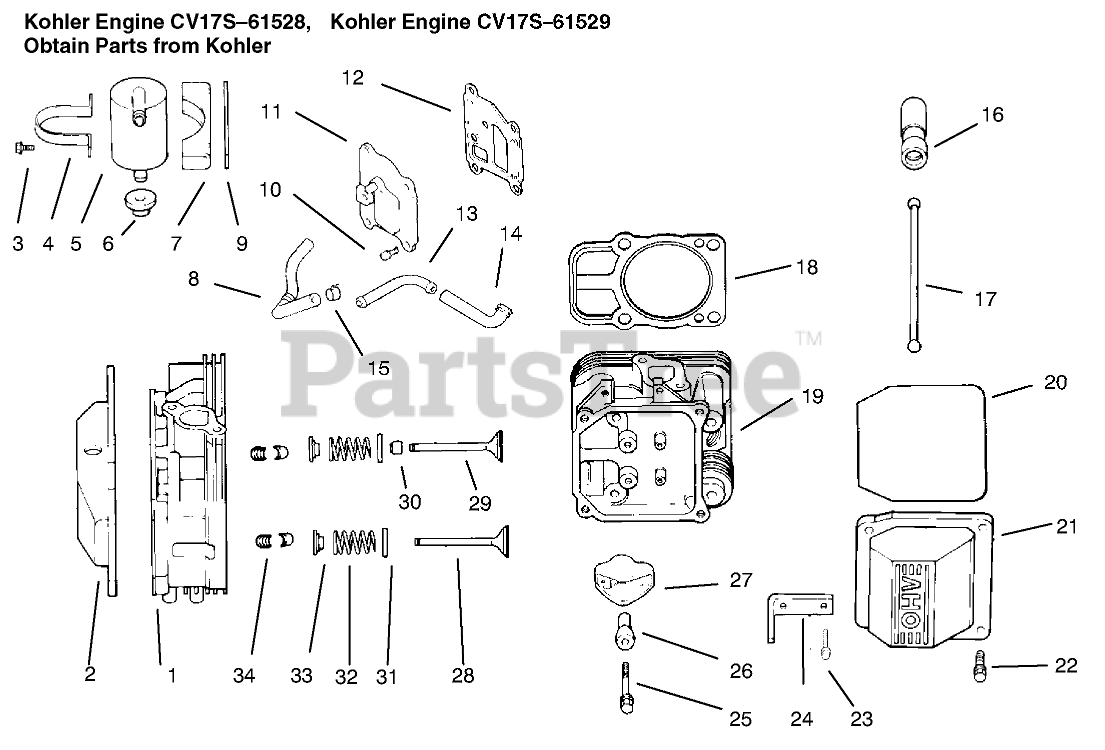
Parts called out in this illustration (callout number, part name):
1	#1 Cyl. Head Asm
2	Kit-Valve Incl 6 20-22
3	Screw-HF
4	Strap-Lifting
5	Kit-Breather Incl 3-9
6	Grommet-Rubber
7	Bracket
8	Hose-Breather
9	Spacer
10	Screw
11	Cover-Breather
12	Gasket-Breather
13	Fitting
14	Hose-Breather
15	Clamp
16	Lifter-Valve
17	Rod-Push
18	Gasket-Cylinder Head
19	#2 Cyl. Head Asm,
20	O Ring
21	Valve Kit
22	Screw
23	Screw
24	Strap-Lifting
26	Pivot-Arm, Rocker
27	Arm-Rocker
28	Valve-Exhaust
28	Valve-Exhaust (.25)
29	Valve-Intake
29	Valve-Intake (.25)
30	Seal-Stem, Valve
31	Retainer-Spring
32	Spring-Valve
33	Cap-Spring, Valve
34	Retainer Kit
